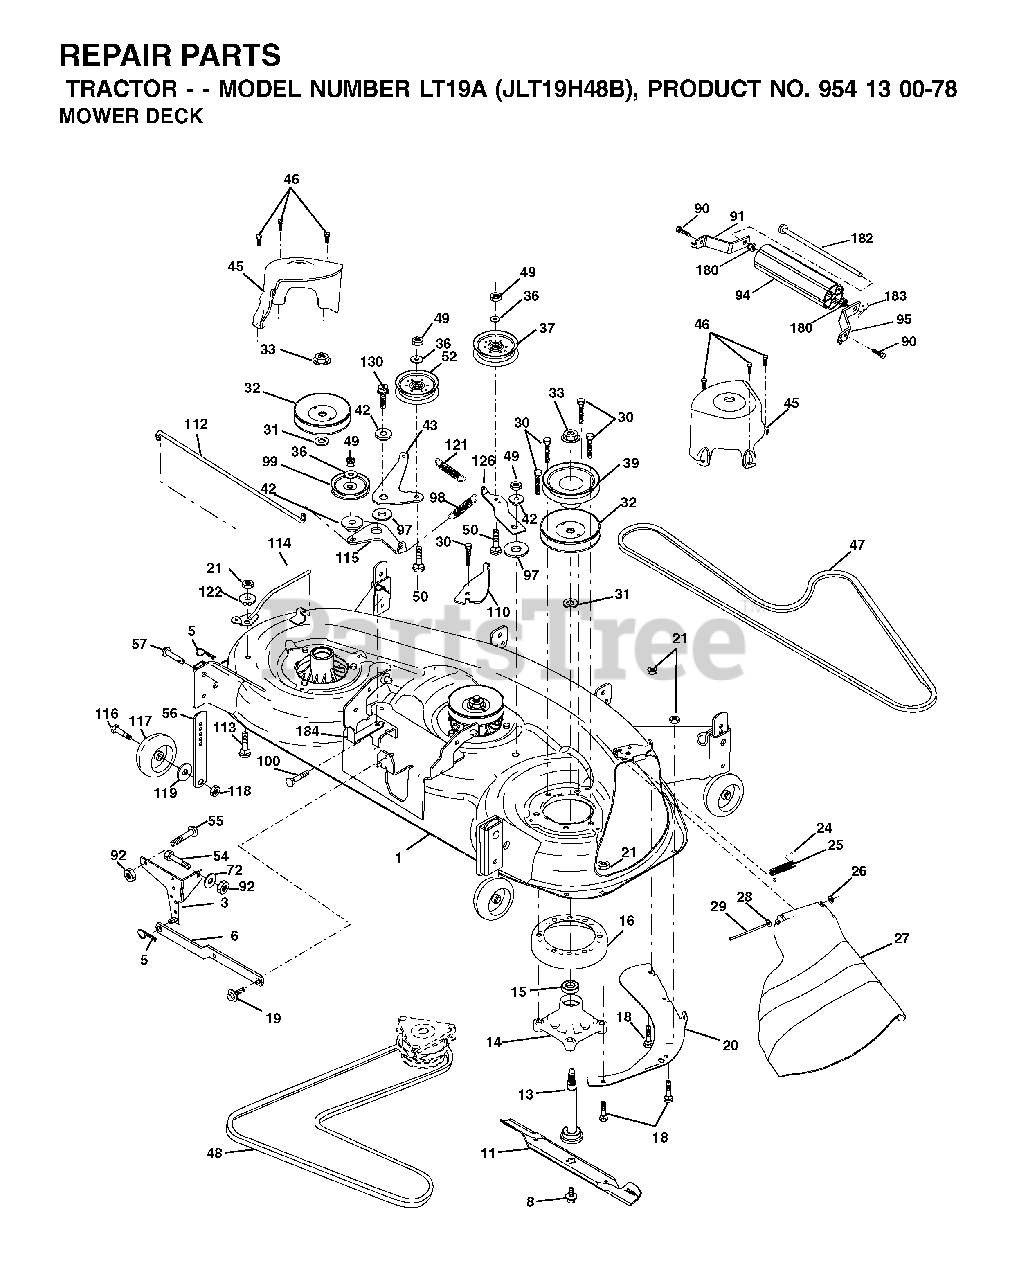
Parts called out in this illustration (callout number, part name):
1	DECK WELDMENT
3	BRKT ASM SWAY BAR
5	RETAINER-SPRNG RB
6	BAR SWAY DECK
8	BOLT 7/16 ASM BLADE
11	48" HI-LIFT BLADE
13	SHAFT ASM W/LOWER BEARING
14	HOUSING, MANDREL 48"
16	STRIPPER, MWR ROUND
17	BOLT
18	BOLT
19	BOLT SHD 5/16-18
20	BAFFLE, VORTEX MWR
21	LOCKNUT
24	CAP-SLEEVE LT
25	SPRING, TORSION
26	NUT PUSH M
27	DEFLECTOR SUBS TO 532 180655
28	WASHER
29	ROD.HINGE
30	SCREW, WASHER HEAD
31	WASHER
32	PULLEY, MANDREL
33	NUT, FLG TOPLOCK 9/16"
37	PULLEY, IDLER, FLAT
39	PULLEY.IDLER.DRIVEN
42	SPACER.RETAINER.MOWER
43	ARM, IDLER SECONDARY
45	COVER, MANDREL DECK
46	SCREW.1/4-20X5/8
47	V-BELT, 48"SECONDARY
48	V-BELT PRIMARY 48"
49	LOCKNUT
50	BOLT.3/8-16X1.50
52	PULLEY.IDLER.FLAT.46.PR.DR.
55	BOLT D
56	BAR.ADJUST.WHEEL.ANTI.SCALP.BL
57	RIVET.PIN.HEAD.YELLOW
72	WASHER
90	BOLT RB
91	BRKT.NOSEROLLER.LH.48"
92	NUT
94	NOSE ROLLER 48"
95	BRKT.NOSEROLLER.RH.48"
97	HARDENED WASHER
98	SPRING PRIMARY DRIVE
99	PULLEY,IDLER"V"
100	BOLT
109	NUT.CROWNLOCK.1/4
110	ARM, SPRING SECONDARY
112	LEVER, TENSION RELIEF LINK
114	LEVER ASM, TENSION RELIEF
115	ARM, SPRING TENSION RELIEF
116	BOLT, SHOULDER
117	WHEEL. GUAGE RALLY
118	LOCKNUT
119	WASHER
121	SPRING SECONDARY DR
122	BUSHING, PIVOT TENSION RELIEF
126	ARM, IDLER PRIMARY DECK
130	SCREW 3/8-16X1
132	SCREW 3/8-16X3/4
180	NUT.71038.31-18.HEX.NYLOCK
182	ROD.ROLLER.NOSE.NARROW.48"
183	SPRING RETAINER
184	KEEPER BELT IDLER PLATED
